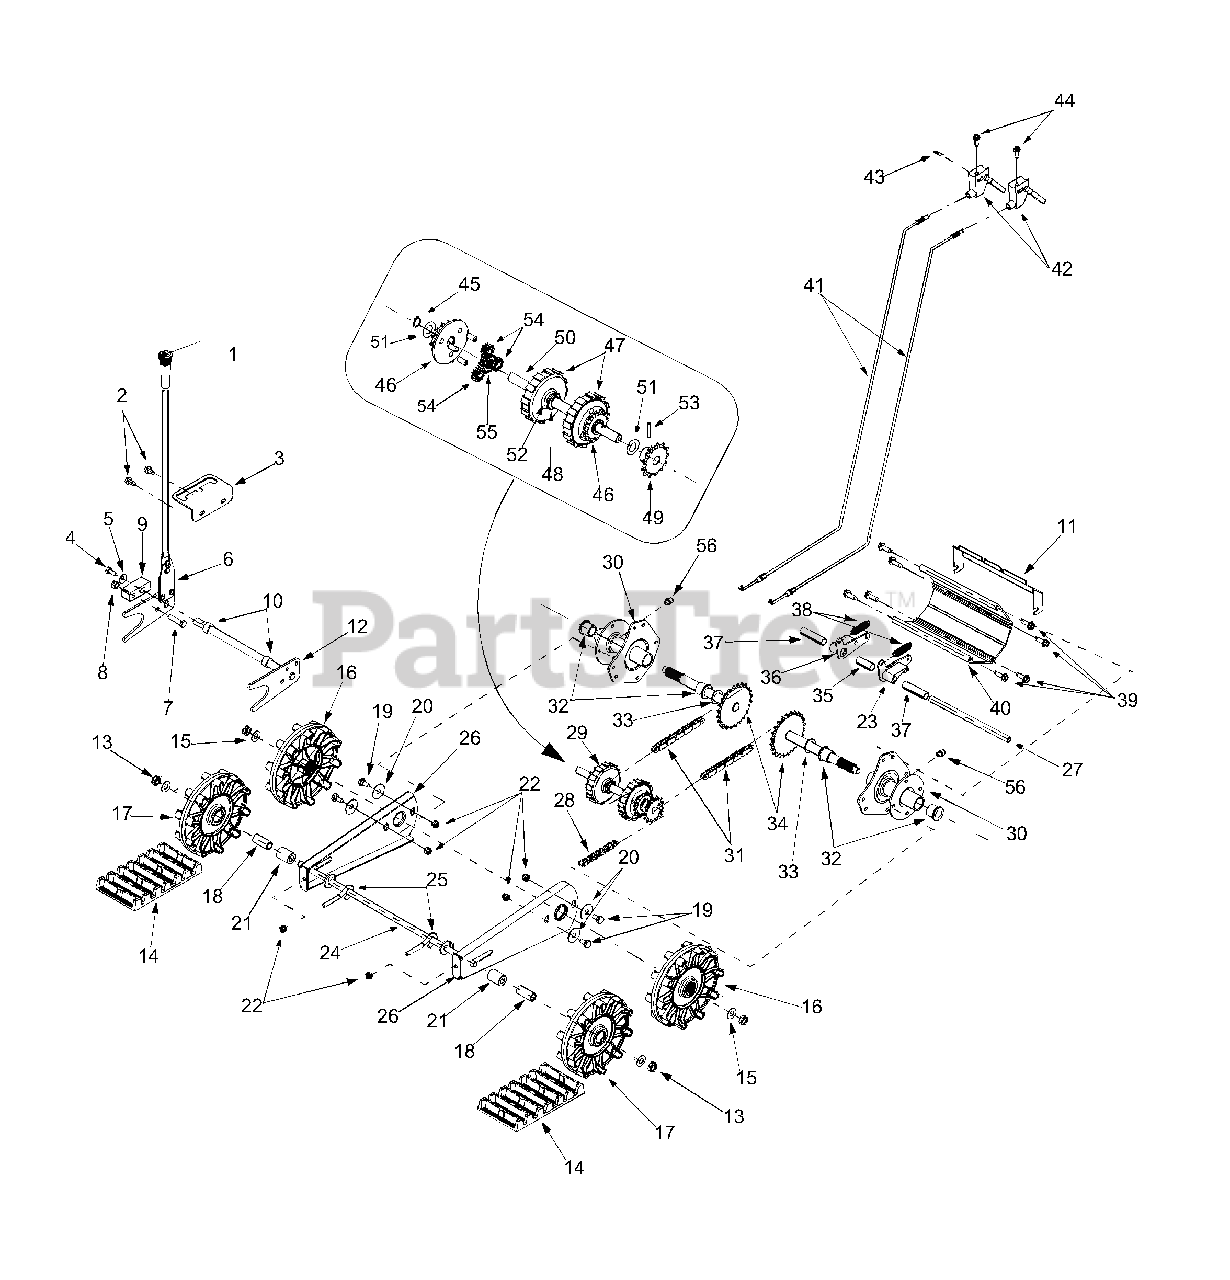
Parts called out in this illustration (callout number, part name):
2	Tap Screw, 5/16-18 x .625
4	Hex Cap Screw, 5/16-24 x .75
5	Bell Washer, .34 ID x .872 OD
7	Hex Cap Screw, 3/8-24 x 1.5
8	Hex Nut, 3/8-24
9	Lift Shaft Drive
10	Spacer, .628 ID x .875 OD x .5
13	Jam Nut, 1/2-20
15	Flat Washer, .5 x 1 x .06
16	Track Drive Wheel
17	Track Idler Wheel
18	Spacer, .51 ID x .75 OD x 1.67
19	Screw, .435 x .178-5/16 x .56
20	Flat Washer, .442 x 1.38 x .06
21	Spacer, .51 ID x 1 OD x 1.34
22	Hex Nut, 5/16-18
23	LH Dogg Assembly
25	Eye Bolt, 5/16-18 x 3
27	Actuator Shaft
32	Flange Bearing
33	Flat Washer, .793 x 1.24 x .06
34	Axle Assembly
35	Spacer, .514 x .630 x 1.59
36	RH Dogg Assembly
37	Spacer, .514 x .630 x 2.44
38	Extension Spring
39	Tap Screw, 5/16-18 x 1
40	Track Housing
41	Steering Cable
42	Steering Trigger
44	Screw, #10-24 x 1.375
45	Retaining Ring
46	Carrier Assembly
48	Retaining Ring
49	13-Tooth Sprocket
50	Track Steering Drive Shaft
51	Flat Washer, .58 x 1.06 x .02
52	Flat Washer, 5/8 x 1 x .03
53	Spiral Pin, 3/16 x 1
54	12-Tooth Gear
55	18-Tooth Gear
56	Grease Fitting, 3/16" Drive
